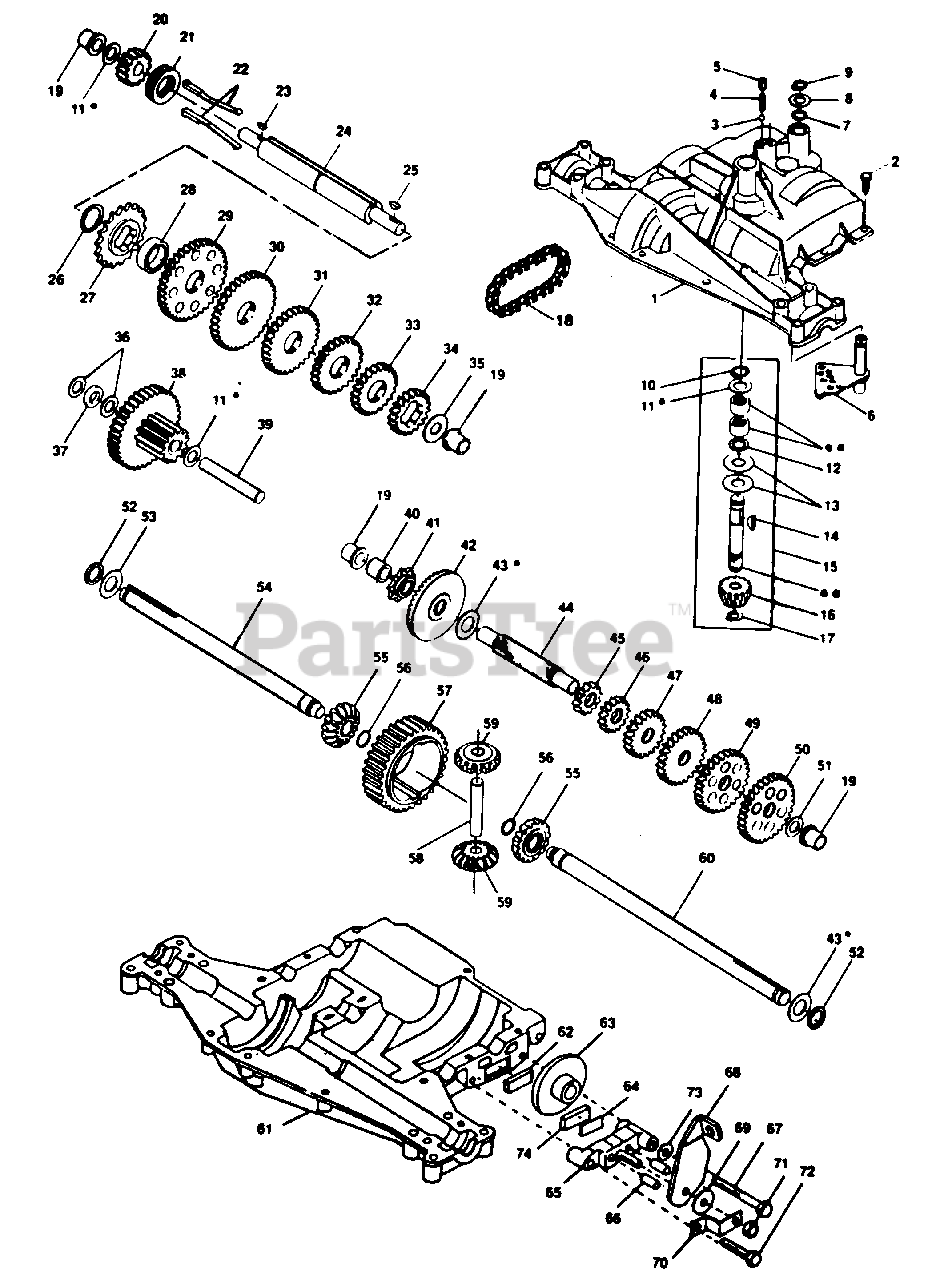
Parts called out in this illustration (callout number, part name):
1	Upper Housing (Dana part number)
2	Tapping Screw (Dana part number)
3	Detent Ball (Dana part number)
4	Detent Spring (Dana part number)
5	Screw Set (Dana part number)
6	Shifter Assembly (Dana part number)
7	O-Ring (Dana part number)
8	Plain Washer .505 x .942 x .006 (Dana part number)
8	Plain Washer .505 x .942 x .010 (Dana part number)
8	Plain Washer .505 x .942 x .015 (Dana part number)
8	Plain Washer .505 x .942 x .020 (Dana part number)
8	Plain Washer .505 x .942 x .026 (Dana part number)
8	Plain Washer .505 x .942 x .030 (Dana part number)
8	Plain Washer .505 x .942 x .040 (Dana part number)
9	Retaining Ring (Dana part number)
10	Retaining Ring (Dana part number)
11	Plain Washer .632 x 1.00 x .010 (Dana part number)
11	Plain Washer .632 x 1.00 x .020 (Dana part number)
11	Plain Washer .632 x 1.00 x .026 (Dana part number)
11	Plain Washer .632 x 1.00 x .031 (Dana part number)
11	Plain Washer .632 x 1.00 x .036 (Dana part number)
11	Plain Washer .632 x 1.00 x .041 (Dana part number)
11	Plain Washer .632 x 1.00 x .046 (Dana part number)
11	Plain Washer .632 x 1.00 x .050 (Dana part number)
11	Plain Washer .632 x 1.00 x .060 (Dana part number)
11	Plain Washer .632 x 1.00 x .082 (Dana part number)
12	O-Ring(Dana part number)
13	Plain Washer
14	#9 Woodruff Key
15	Input Shaft Assembly Kit (Dana part number)
16	14T Bevel Pinion (Dana part number)
17	Retaining Ring (Dana part number)
18	24 Pitches Chain (Dana part number)
19	Flange Bearing (Dana part number)
20	14T Spur Gear
21	Clutch Collar (Dana part number)
22	Clutch Key (Dana part number)
23	#3 Woodruff Key
24	Intermediate Shaft (Dana part number)
25	#61 Woodruff Key (Dana part number)
26	Retaining Ring (Dana part number)
27	18T Sprocket (Dana part number)
28	Spacer (Dana part number)
29	37T Spur Gear
30	35T Spur Gear
31	30T Spur Gear (Dana part number)
32	25T Spur Gear
33	22T Spur Gear (Dana part number)
34	19T Spur Gear (Dana part number)
35	Plain Washer (Dana part number)
36	Plain Washer .632 x 1.00 x .026 (Dana part number)
37	Spacer (Dana part number)
38	Comb. Gear Assembly (Dana part number)
39	Idler Shaft (Dana part number)
40	Spacer (Dana part number)
41	9T Sprocket (Dana part number)
42	42T Bevel Gear (Dana part number)
43	Plain Washer .758 x 1.12 x .010 (Dana part number)
43	Plain Washer .758 x 1.12 x .015 (Dana part number)
43	Plain Washer .758 x 1.12 x .020 (Dana part number)
43	Plain Washer .758 x 1.12 x .025 (Dana part number)
43	Plain Washer .758 x 1.25 x .020 (Dana part number)
43	Plain Washer .758 x 1.25 x .025 (Dana part number)
43	Plain Washer .758 x 1.25 x .031 (Dana part number)
43	Plain Washer .758 x 1.25 x .035 (Dana part number)
43	Plain Washer .758 x 1.25 x .040(Dana part number)
43	Plain Washer .758 x 1.25 x .045 (Dana part number)
43	Plain Washer .758 x 1.25 x .050 (Dana part number)
43	Plain Washer .758 x 1.25 x .055 (Dana part number)
43	Plain Washer .758 x 1.25 x .062 (Dana part number)
44	Drive Shaft (Dana part number)
45	Gear Spur 12T (Dana part number)
46	15T Spur Gear (Dana part number)
47	20T Spur Gear (Dana part number)
48	25T Spur Gear (Dana part number)
49	28T Spur Gear (Dana part number)
50	31T Spur Gear (Dana part number)
51	Plain Washer (Dana part number)
52	Felt Seal (Dana part number)
53	Plain Washer (Dana part number)
54	L.H. Axle (Dana part number)
55	15T Miter Gear
56	Retaining Ring (Dana part number)
57	32T Spur Gear (Dana part number)
58	Cross Shaft (Dana part number)
59	15T Miter Gear
60	R.H. Axle (Dana part number)
61	Lower Housing (Dana part number)
62	Friction Puck (Dana part number)
63	Brake Disc.(Dana part number)
64	Spacer (Dana part number)
65	Brake Jaw (Dana part number)
66	Dowel Pin (Dana part number)
67	Tapping Screw (Dana part number)
68	Actuating Lever
69	Plain Washer
70	Anti-Rotation Bracket (Dana part number)
71	Locknut (Dana part number)
72	Tapping Screw (Dana part number)
73	Plain Washer
74	Friction Puck (Dana part number)
75	Grease (Dana part number)
